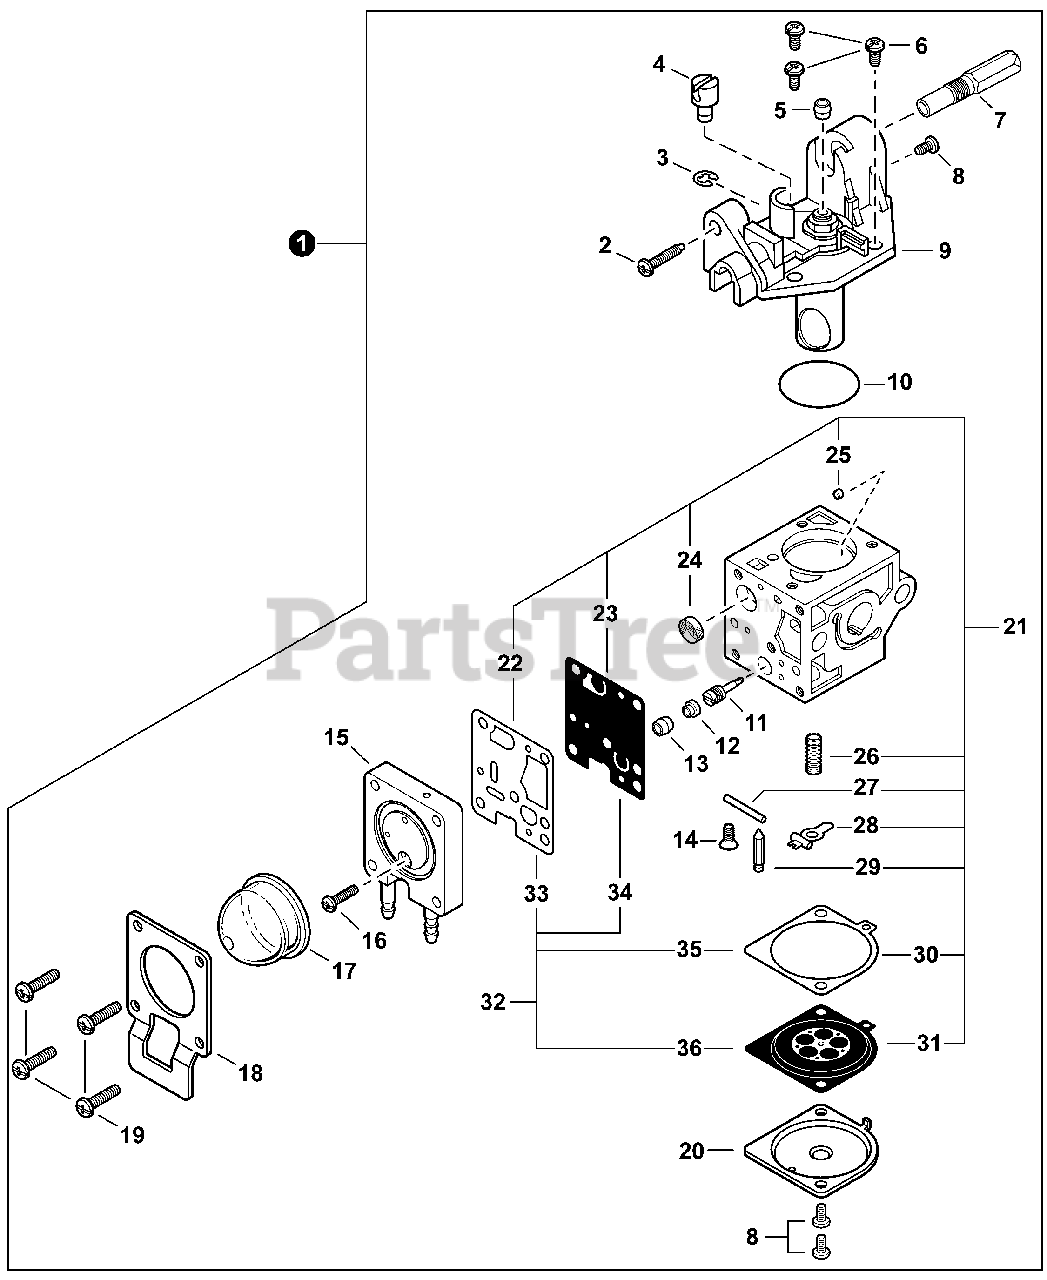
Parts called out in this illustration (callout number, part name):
1	CARBURETOR - RB-K70A
2	SCREW, IDLE ADJUST
7	ADJUSTER, THROTTLE CABLE
9	COVER ASSY, ROTOR
11	NEEDLE, HIGH SPEED
12	CAP, LIMITER
15	BODY ASSY, PURGE
17	BULB, PURGE
18	RETAINER, PURGE BULB
20	COVER, METERING DIAPHRAGM
21	REPAIR KIT, CARBURETOR
22	GASKET, PUMP
23	DIAPHRAGM, PUMP
24	SCREEN, FUEL INLET
25	GUIDE, ROLLER
26	SPRING, METERING LEVER
27	PIN, METERING LEVER
28	LEVER, METERING
29	VALVE, INLET NEEDLE
30	GASKET, METERING DIAPHRAGM
31	DIAPHRAGM, METERING
32	GASKET / DIAPHRAGM KIT
33	GASKET, PUMP
34	DIAPHRAGM, PUMP
35	GASKET, METERING DIAPHRAGM
36	DIAPHRAGM, METERING
